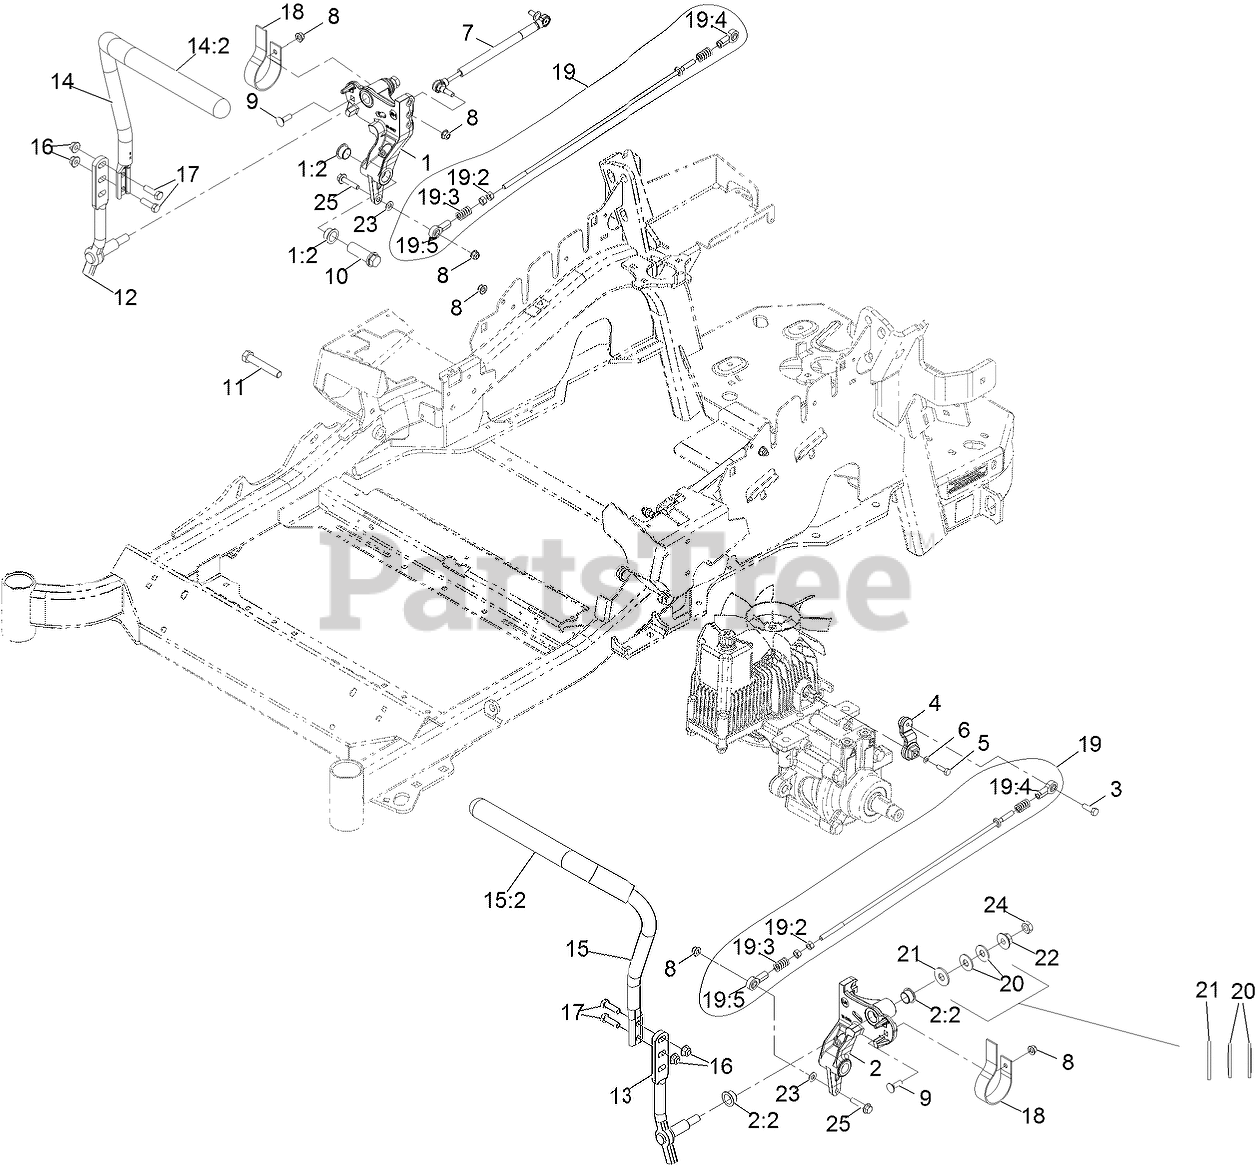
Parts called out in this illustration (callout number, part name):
1	RH MOTION CONTROL AND BUSHING ASM
1:2	BUSHING-FLANGE
2	LH MOTION CONTROL AND BUSHING ASM
2:2	BUSHING-FLANGE
3	SCREW-HH, THREAD LOCKING
4	ARM-CONTROL, PUMP
5	SCREW-HH
6	WASHER-SPRING
7	DAMPER-CONTROL, MOTION
8	NUT-HF, NI
9	BOLT-CARR
10	HUB-THREADED
11	SCREW-HH
12	LEVER-CONTROL MOTION, RH
13	LEVER-CONTROL MOTION, LH
14	HANDLE- RH W/GRIP
14:2	GRIP-LEVER, CONTROL
15	ASM-HANDLE-LH
15:2	GRIP-LEVER, CONTROL
16	NUT-HF, NI
17	SCREW-HH
18	SPRING-LEAF
19	PUMP LINKAGE REAR ASM
19:2	NUT-HEX
19:3	SPRING-COMPRESSION
19:4	BALLJOINT-LH
19:5	BALLJOINT-RH
20	WASHER-SPRING
21	WASHER-FLAT
23	WASHER-PLAIN
24	NUT-JAM
25	SCREW-HHF
